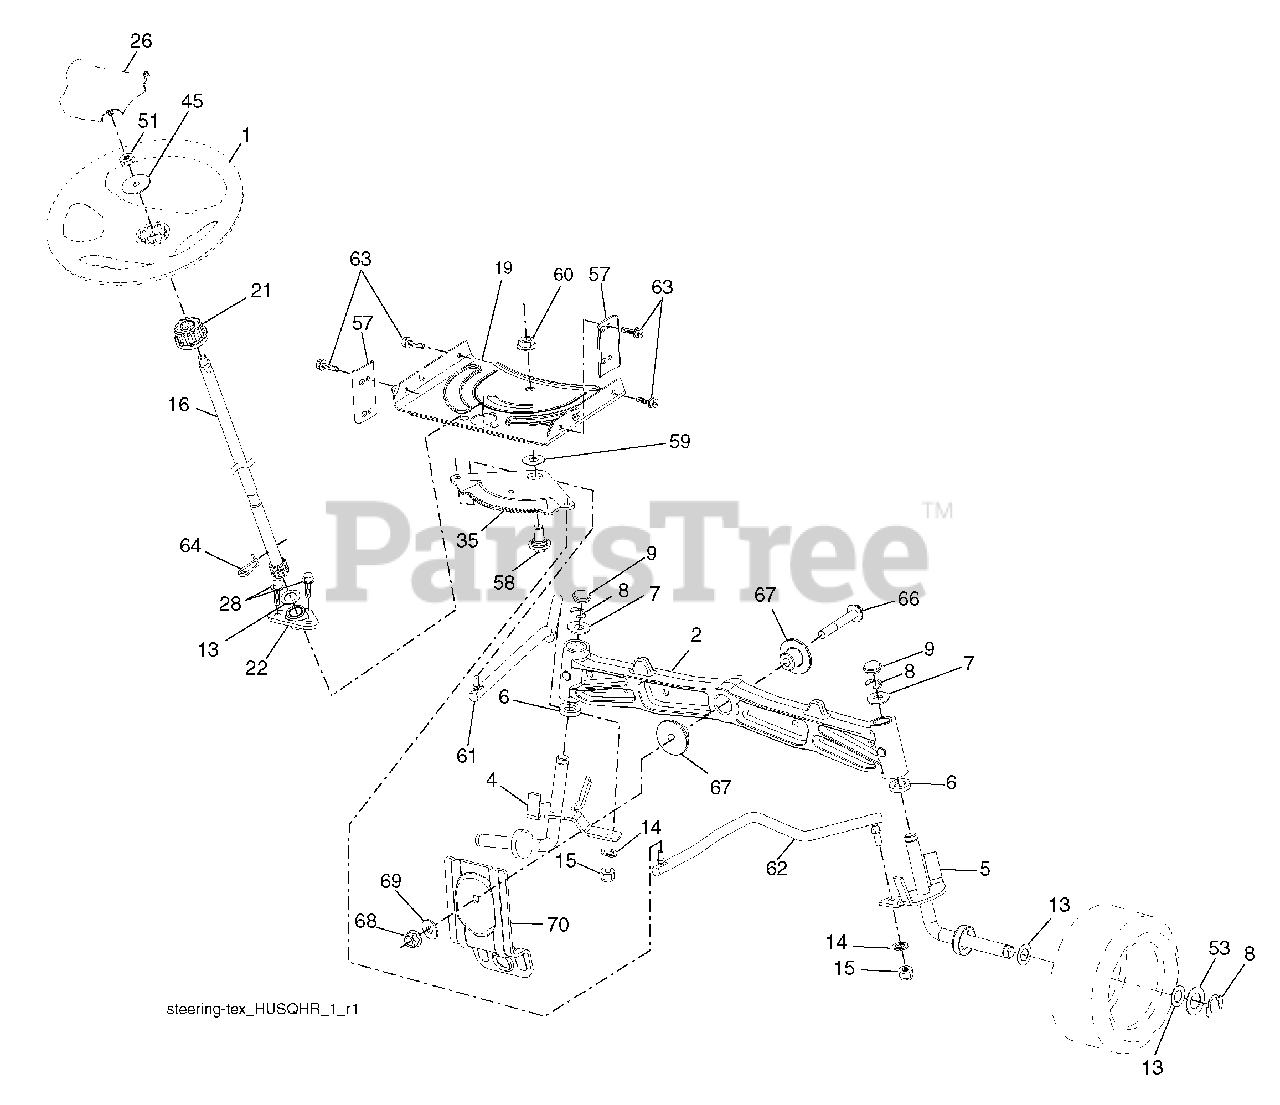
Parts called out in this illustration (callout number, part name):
1	Wheel, Steering
2	Axle Cast Iron
4	Spindle Asm., LH
5	Spindle Asm., RH
6	Washer, Thrust
7	Washer 25/32 x 1-5/8 x 16 Ga.
8	Ring, Klip #T5304-75
9	Cap, Spindle
13	Washer 25/32 x 1-1/4 x 16 Ga.
14	Washer, Lock Hvy Hlcl Spr 3/8
15	Nut, Crown Lock 3/8-24 unf
16	Shaft Steering
19	Plate Steering
21	Adapter, Wheel Steering
22	Steering Support Lower
26	Insert, Wheel Steering
28	Screw 3/8-16 x 3/4
35	Gear, Sector Plate
45	Washer 9/16 ID x 2-3/8 OD 12 Ga.
51	Nut Hex Jam Toplock 1/2-20 unf
53	Washer Hardened .793 x 1.637 x .060
57	Bracket Upstop
58	Bolt Shoulder Sector Pivot CFM
59	Washer Thrust Sector Steering
60	Nut Flange Lock 5/8-11
61	Draglink, LH
62	Draglink, RH
63	Screw 5/16-18 x 3/4
64	Retainer Clip Spring Steering
66	Bolt Hex Fghd 7/16-14 x 3 Serr
67	Bushing PM Front Axle
68	Nut Lock Flange 7/16-14 Gr. 5
69	Washer 1.5 x .505 x .118
70	Bracket Deck Susp. Front
